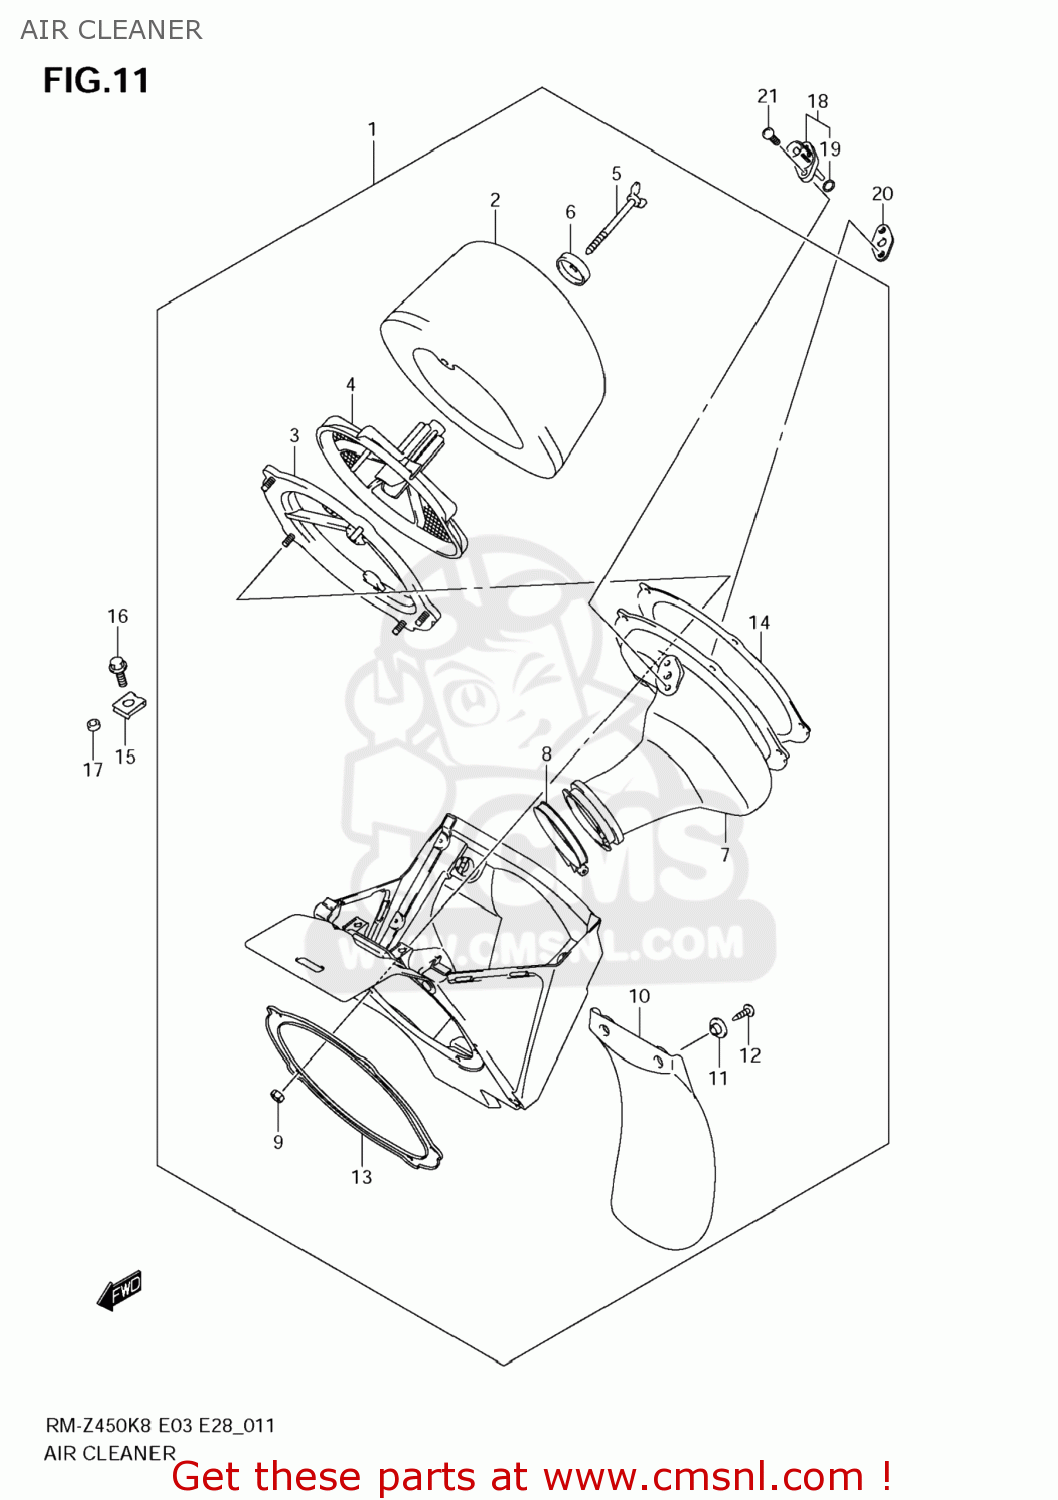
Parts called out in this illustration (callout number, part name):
1	CLEANER ASSY,AIR
2	FILTER ASSY
3	BASE,FILTER
4	HOLDER,FILTER
5	BOLT,WING
6	WASHER,AIR CLEANER
7	TUBE,OUTLET
8	CLAMP,AIR CLEANER
9	NUT
10	MUDGUARD
11	COLLAR
12	SCREW
13	PLATE
14	GASKET (NAS)
15	NUT
16	BOLT
17	SPACER(6.2X10X2.2)
18	SENSOR,AIR TEM
19	O RING
20	BRACKET,AIR TEMP SENSOR
21	SCREW
